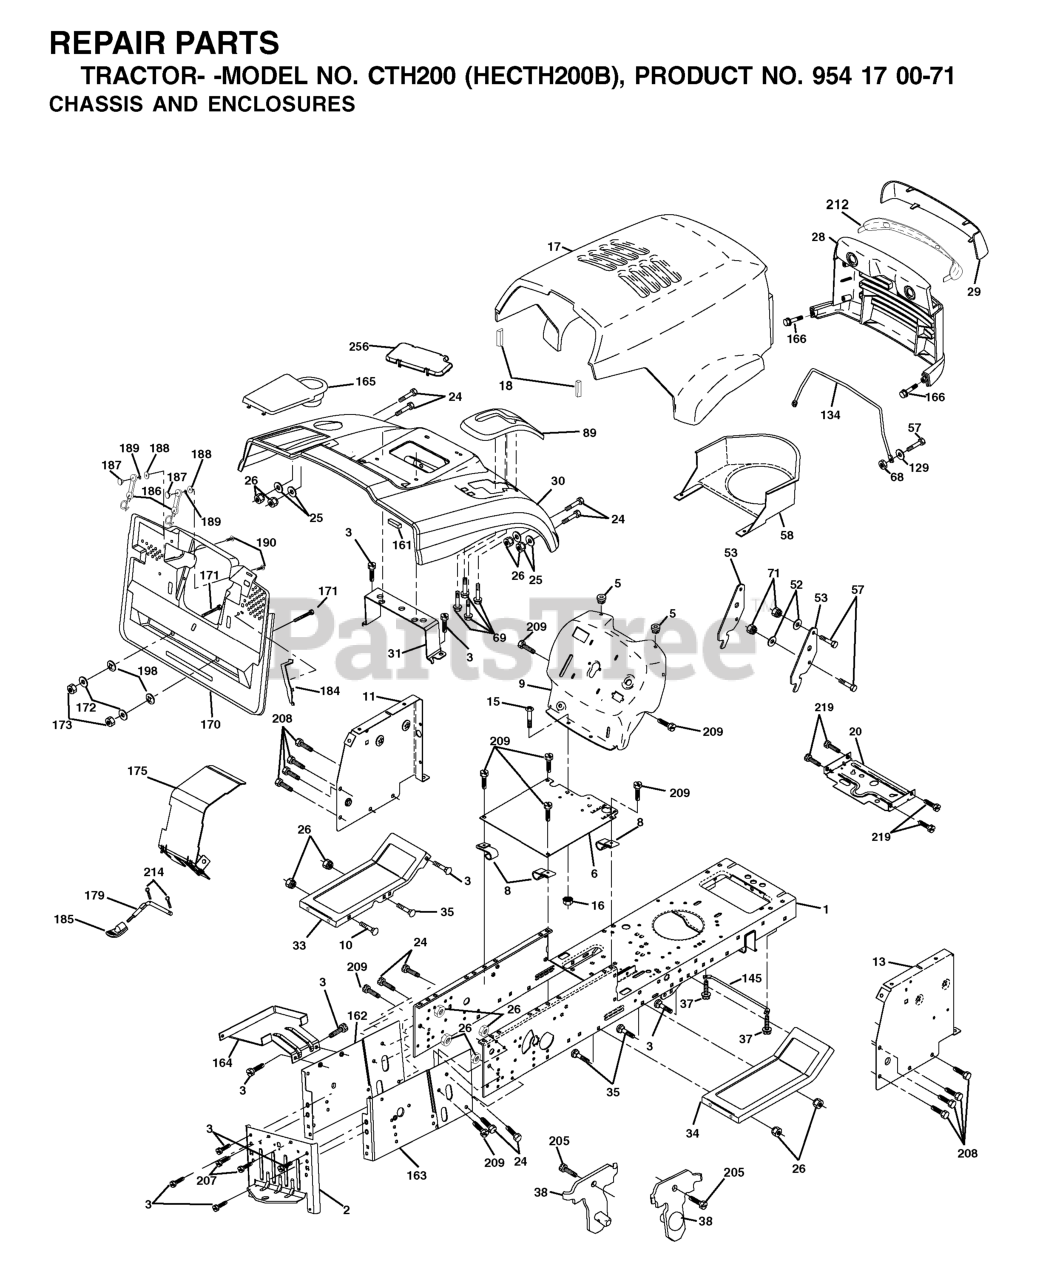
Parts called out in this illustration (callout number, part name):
2	DRAWBAR
3	SCREW 3/8-16X3/4
5	BUMPER.RUBBER.HOOD
6	SADDLE FLAT
8	CLIP,INSULATOR
10	BOLT D
11	PANEL.DASH.LH.LTX
13	PANEL ASM, DASH RH
15	Screw, Machine, Truss Head 5/16-18 UNC x 3/4
16	NUT
17	HOOD
18	BUMPER HOOD T
20	PLATE MTG.BATTERY/FUEL TANK
25	WASHER
26	NUT
28	GRILL
29	LENS
31	BRACKET SUPPORT FENDER
33	FOOTREST PNT LH
34	FOOTREST PNT RH
37	Screw 5/16-18 x 1/2 Hex, Self Tapping 5/16-18 x 1/2
38	BRACKET ASM PIVOT MOWER REAR
53	BRACKET PNT PICK OFF LT/PL
57	BOLT
58	DUCT, INTAKE AIR
68	NUT
69	SCREW.HI-LO.CONSOLE
71	NUT.CROWNLOCK.1/4
89	COVER.BATTERY.CRD.GREY
134	ROD SUPPORT HOOD LT/PL HUS.
145	ROD PIVOT CHASSIS/HOOD
161	EXTRUSION BUMPER (3 2) (2 2)
162	BRACKET
163	BRACKET EXTEN CHASSIS RH CRD
165	RP.COVER.BATTERY.CRD.GREY
166	SCREW
172	WASHER
184	BRACKET.ACTUATOR.BAGGER.SRD
186	LATCH ASSY
187	WELDNUT
189	LOCKWASHER #10
190	SCREW
207	SCREW, 5/16-18 X 1/2
208	SCREW 3/8-16X1/2
209	SCREW, 3/8-16X3/4
212	INSERT LENS REFLECTOR
214	RETAINER M
215	SCREW 5/16-18X1/2"
219	SCREW
